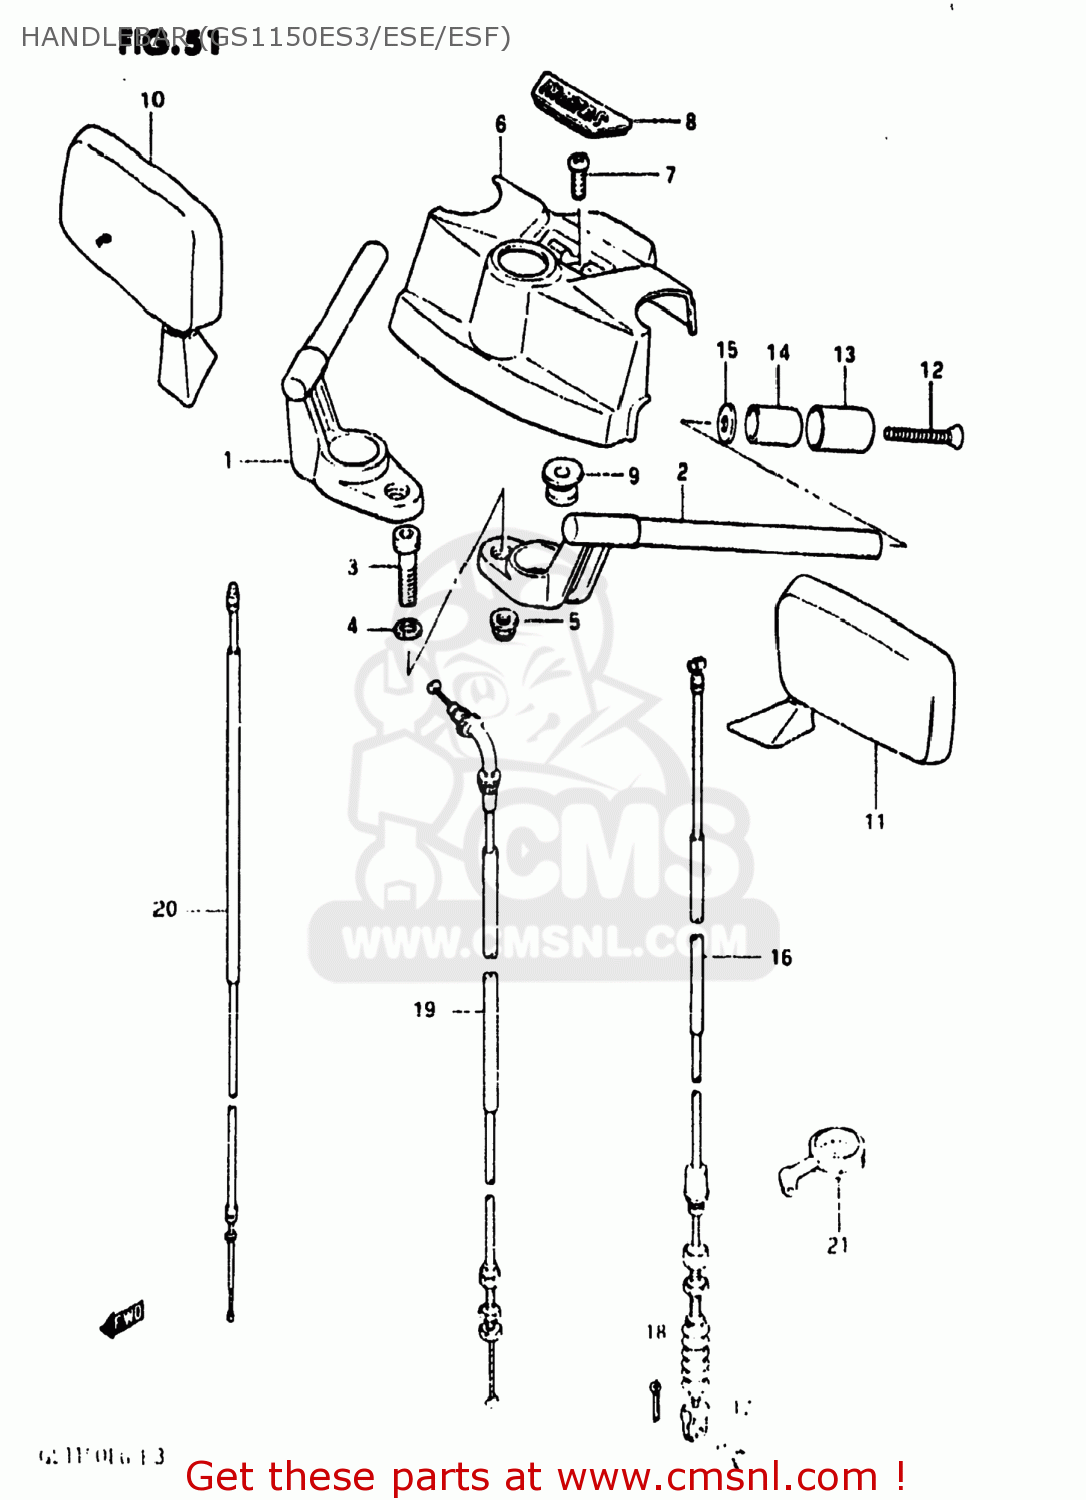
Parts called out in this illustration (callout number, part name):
1	HANDLEBAR,RIGHT
2	HANDLEBAR,LEFT
3	BOLT(10X50)
4	WASHER
5	NUT 10MM
6	PAD,HANDLE
7	SCREW
8	CAP,HANDLE PAD
9	CUSHION,METER BRACKET
10	MIRROR ASSEMBLY,RIGHT
11	MIRROR ASSEMBLY,LEFT
12	SCREW
13	CAP,BALANCER
14	BALANCER,HANDLE
15	SPACER,BALANCER
16	CABLE ASSY,CLUTCH
17	PIN(L:15)
18	PIN
19	CABLE ASSEMBLY,THROTTLE
20	CABLE COMP,STARTER
21	GAUGE ASSY,AIR PRESSURE
